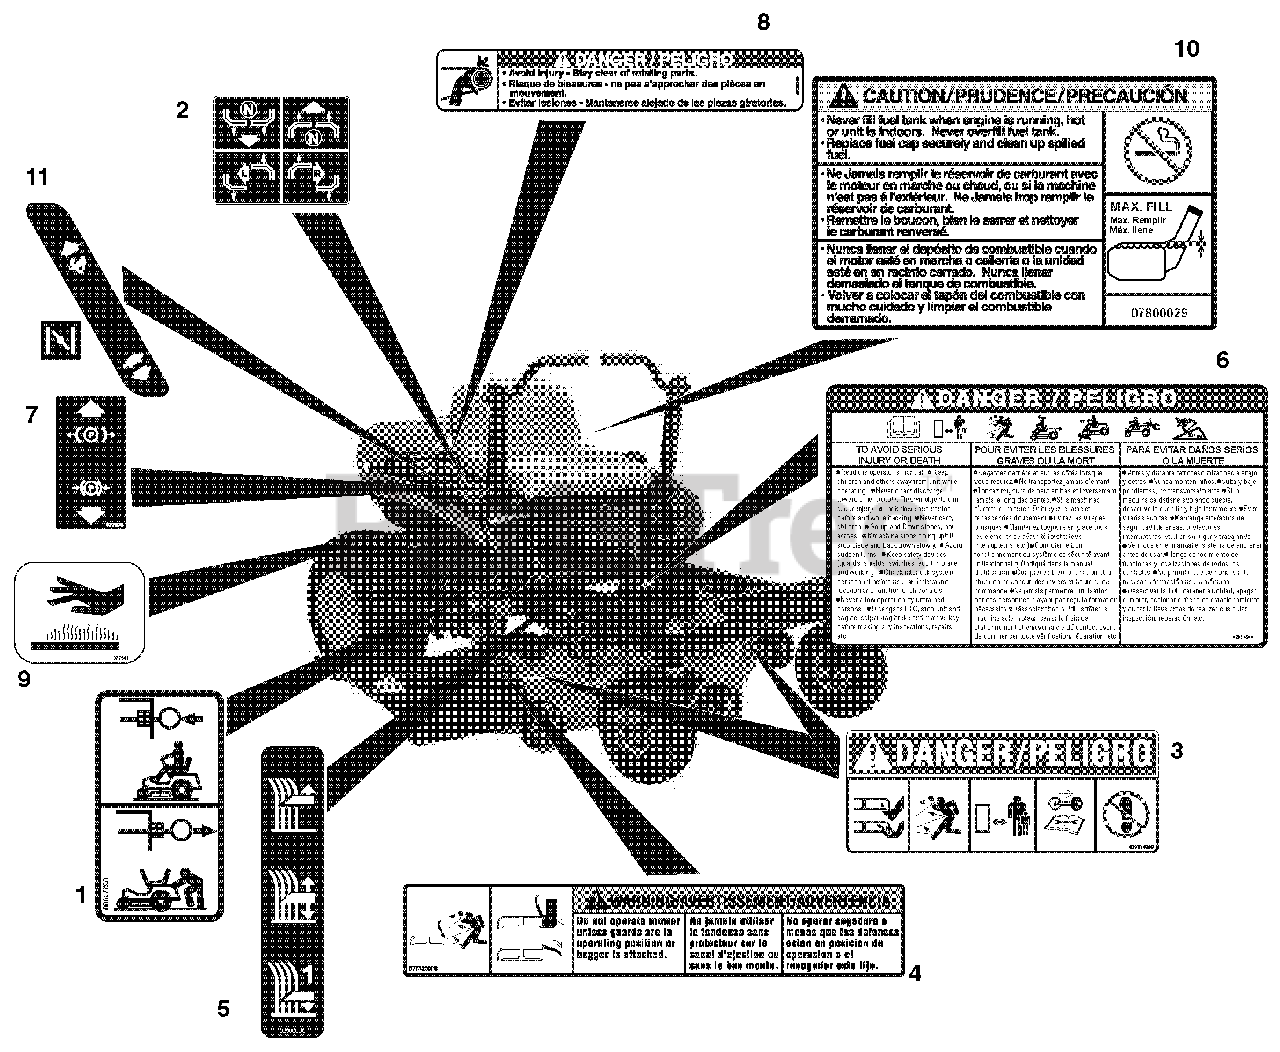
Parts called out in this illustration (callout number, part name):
1	Decal, Transmission Disconnect
2	Decal, Instructional Steering
3	Decal, Mower Pan Head Danger
4	Decal, Warning
5	Decal, Cut Height
6	Decal, Bilingual Danger
7	Decal, Parking Brake Lever
8	Decal, Danger
9	Decal, Hot Surface
10	Decal, Fuel Warning
11	Decal, Control
